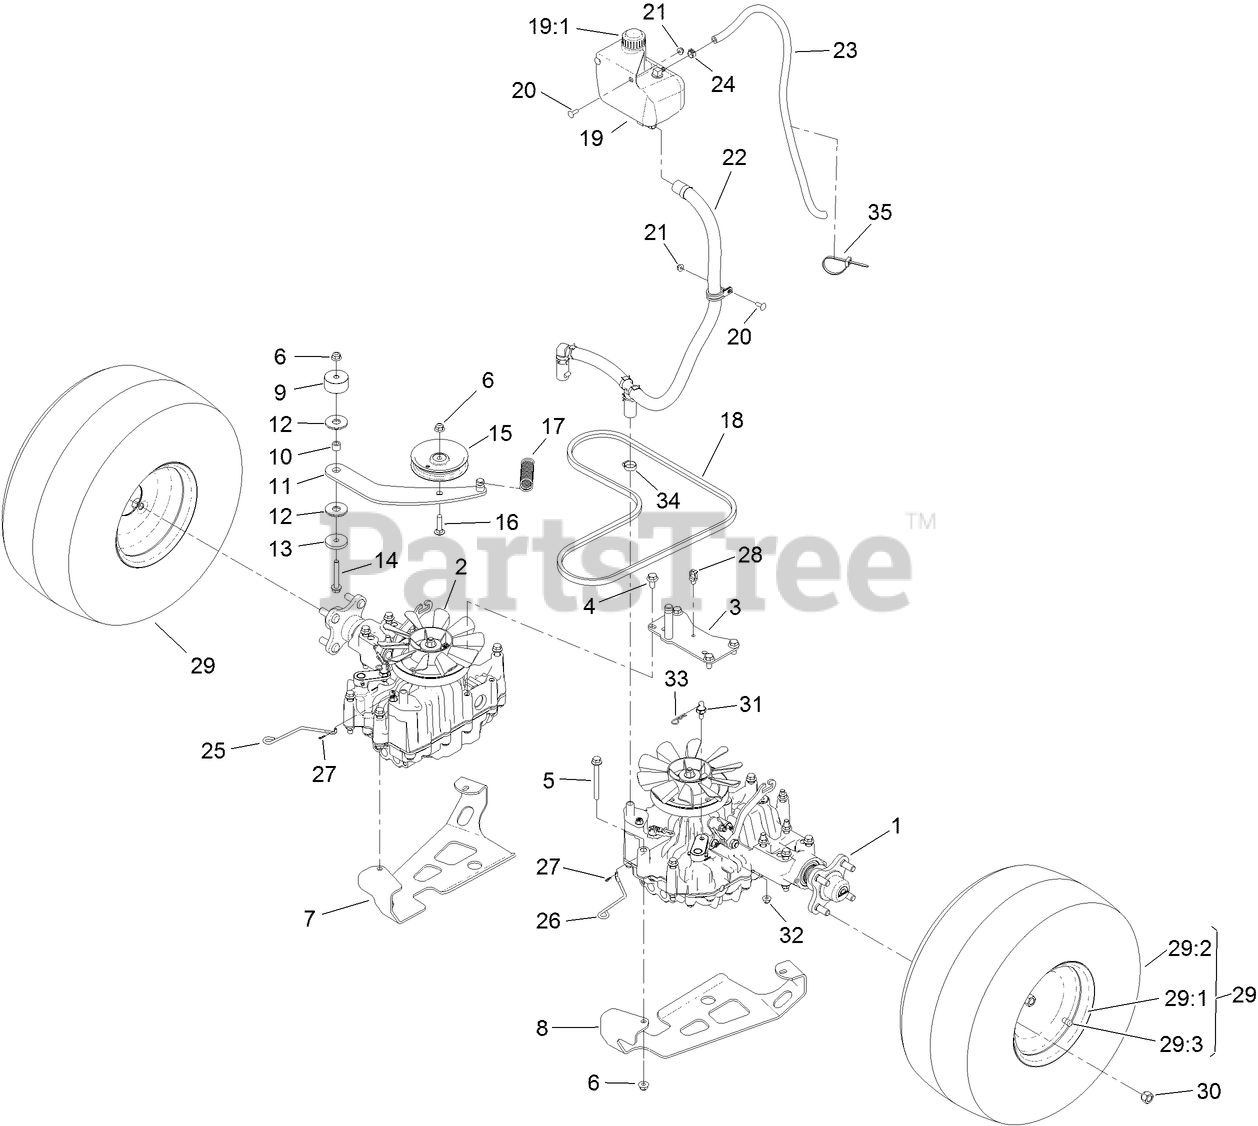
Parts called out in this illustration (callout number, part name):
1	TRANSAXLE-LH
2	TRANSAXLE-RH
3	SUPPORT-TRANSAXLE
4	SCREW-HHF
5	SCREW-HHF
6	NUT-HF, NI
7	PLATE-SKID, TRANSMISSION (RH)
8	PLATE-SKID, TRANSMISSION (LH)
9	SPACER
10	BUSHING-LEVER, LIFT
11	ARM-IDLER
12	WASHER-FRICTION, COMPOSITE
13	WASHER-PLAIN
14	SCREW-HHF
15	PULLEY-IDLER
16	SCREW-CARR
17	SPRING-EXTENSION
18	BELT-V
19	TANK-HYD
19:1	CAP-VENTED
20	SCREW-CARR
21	NUT-HF
22	HYD HOSE ASM
23	HOSE-FUEL
24	CLAMP-HOSE
25	ROD-BYPASS, RH
26	ROD-BYPASS, LH
27	PIN-HAIR
28	CLIP-TIE
29	WHEEL AND TIRE ASM
29:1	RIM-8 INCH, GRAY
29:2	TIRE
29:3	STEM-VALVE
30	NUT-LUG
31	SPACER-HEX
32	NUT-HF, NI
33	PIN-COTTER
34	CLAMP-DRIVE, WORM
35	TIE-CABLE
